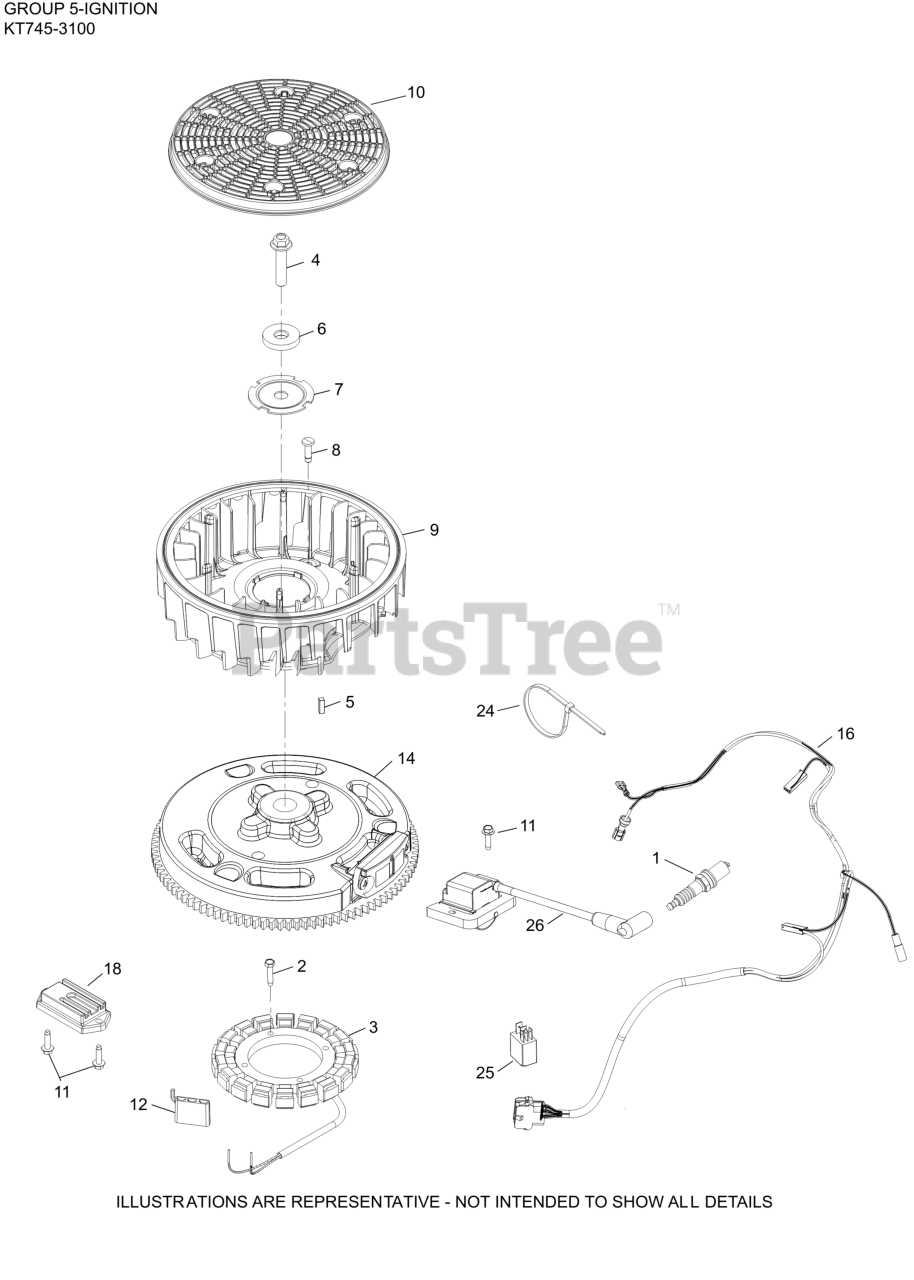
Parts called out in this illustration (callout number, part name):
1	SPARK PLUG, RFI
2	SCREW, THREAD FORMING
3	KIT, 15 / 20 AMP STATOR
4	SCREW, HEX FLANGE
5	KEY, SQUARE
6	WASHER, FLAT
7	PLATE, FAN MOUNTING
8	RETAINER, FLYWHEEL FAN
10	SCREEN, GRASS
11	SCREW, THD FRM-USE 25 086 473-S
12	CONNECTOR
14	FLYWHEEL ASSEMBLY
16	HARNESS, WIRING ASSEM.W/FUEL SHUT DOWN
18	REG/RECT12/15A HALF-WAVE STD-(#2540347S)
26	MODULE, MAGNETO DIGITAL IGNITION
